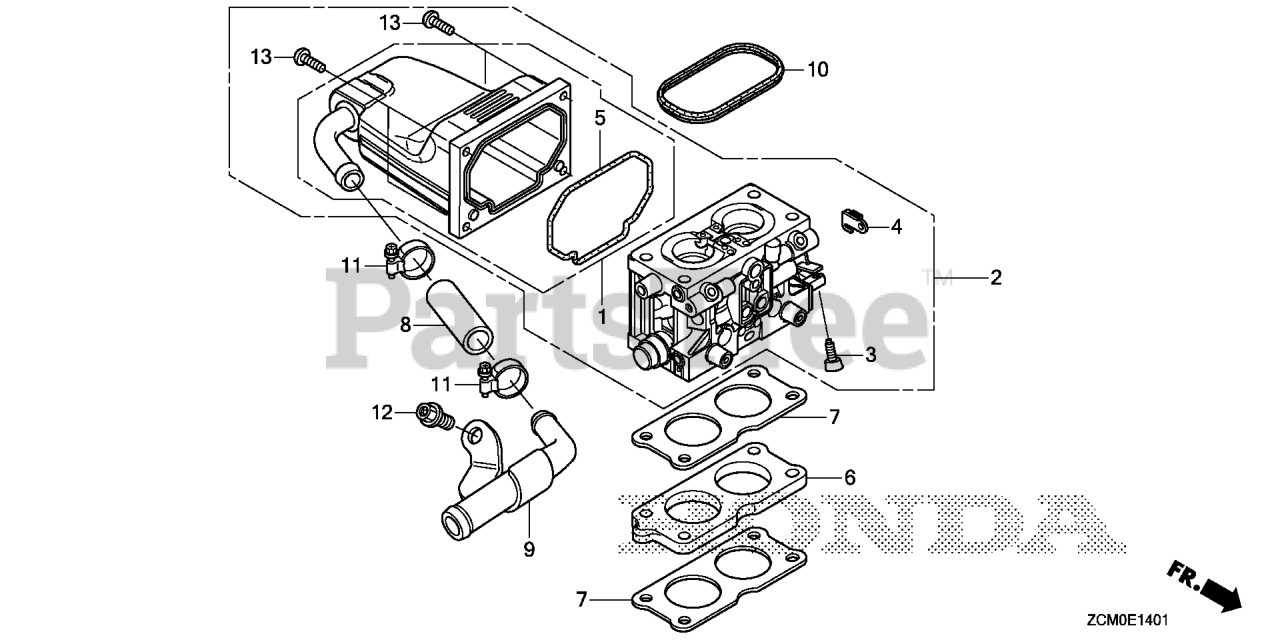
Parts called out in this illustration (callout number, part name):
1	CHAMBER SET, FLOAT
2	CARBURETOR ASSY. (BKL2A B)
3	SCREW, THROTTLE STOP
4	ARM, THROTTLE LINKAGE
5	GASKET, FLOAT CHAMBER
6	INSULATOR, CARBURETOR
7	GASKET, CARBURETOR
8	HOSE, FUEL
9	JOINT, FUEL
10	GASKET, AIR CLEANER
11	CLAMP A, WATER HOSE
12	BOLT, FLANGE (8X16)
13	SCREW, PAN (4X14)
